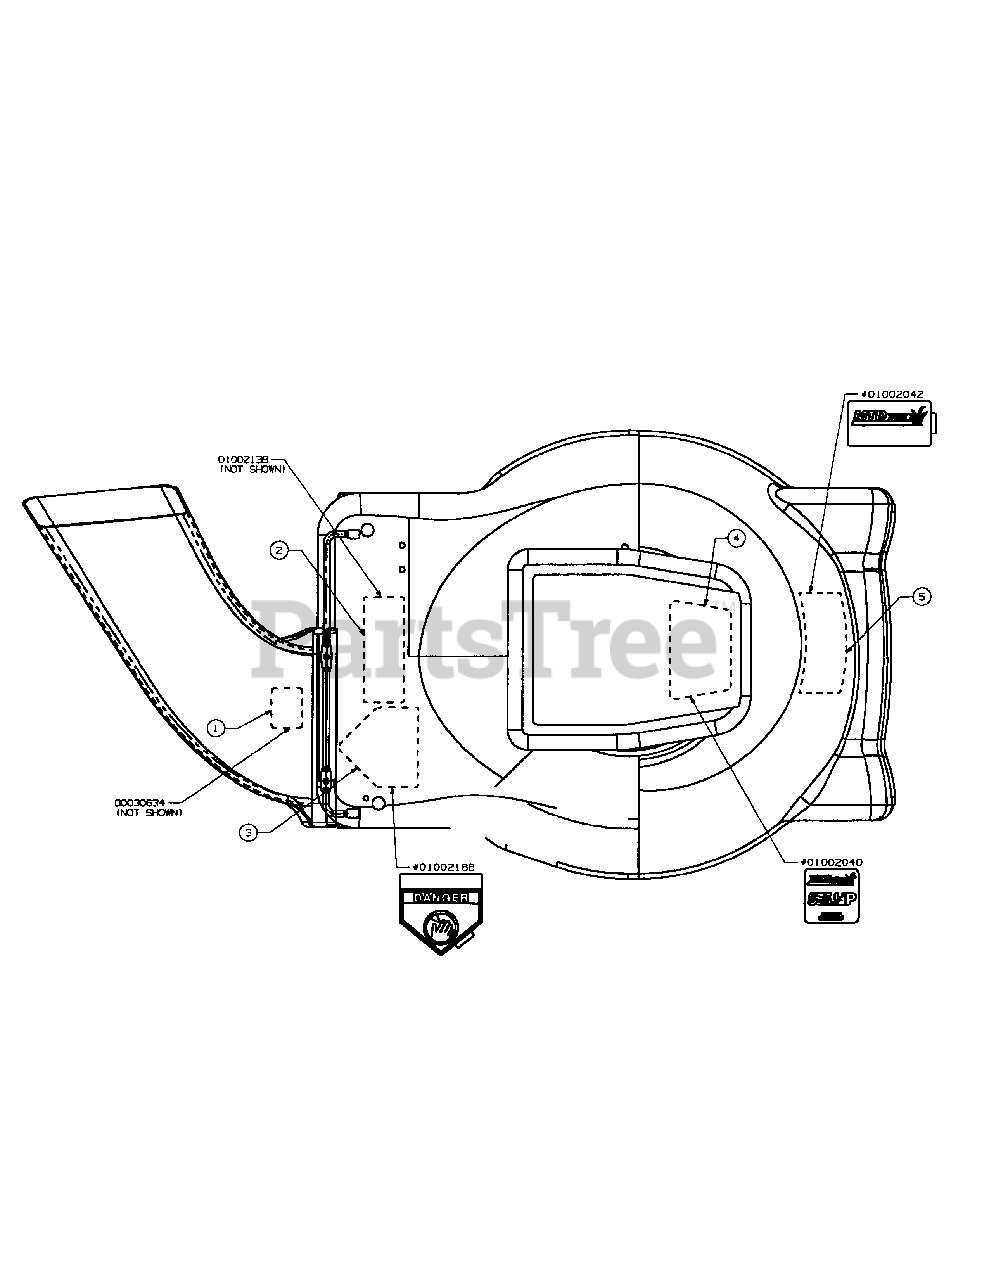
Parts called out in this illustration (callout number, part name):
1	LBL: DANGER, ROTATING BLADE
2	LBL: DANGER, AVOID SERIOUS
3	LBL: DANGER, HANDS & FEET
4	LBL: POWERED BY KAWASAKI
5	LBL: 5.5HP/21", 3-SPEED
